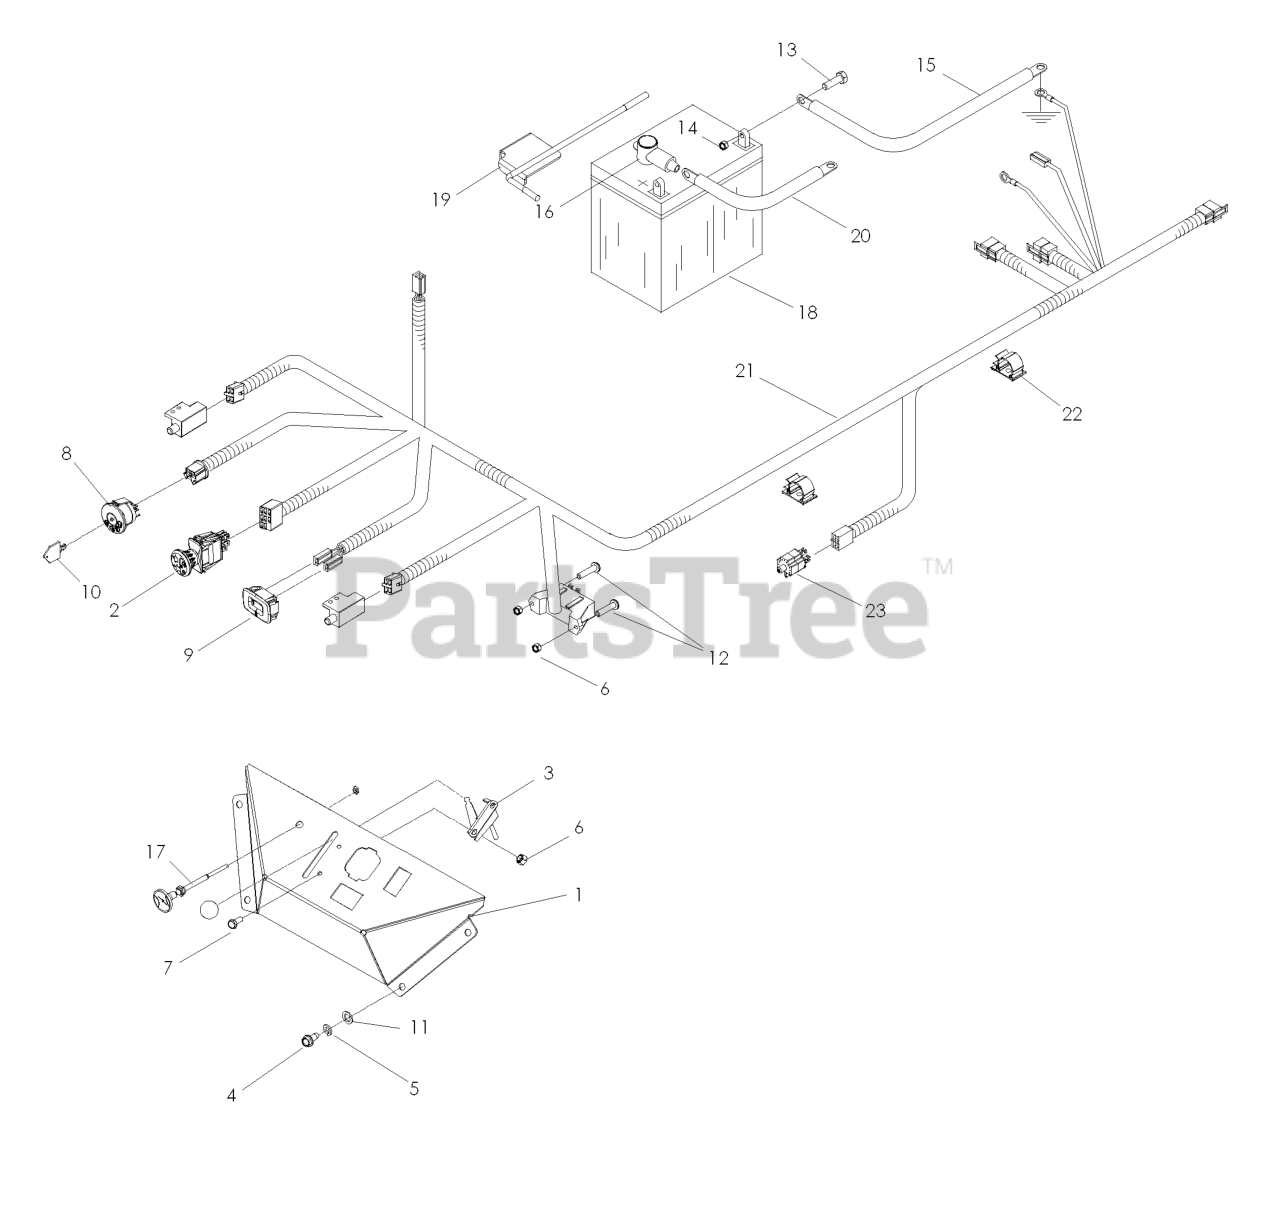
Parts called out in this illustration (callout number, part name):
1	CONSLE, ORANGE
2	SWITCH, PTO 10 AMP
3	THROTTLE CABLE
4	SCREW 1/4 X 5/8
5	LOCKWASHER 1/4"
6	NUT 10-24 NYLOC
7	HCS #10-24 X 1/2
8	RP IGNITION SWITCH
9	HOUR METER
10	KEY
11	WASHER 1/4 FLAT
12	SCREW, #1--24 X 1/2 SLOTTED
13	HCS 5/16C X 3/4
14	NUT 5/16 NYLOC
15	CABLE-NEGATIVE
17	CONTROL-CHOKE 51"
18	BATTERY, 12 V 330 AMP
19	BATTERY HOLD DOWN
20	CABLE POSITIVE, LONG
21	HARNESS, WIRING LZ/IZ
22	PUSH-MOUNT WIRE CLIP
23	SWITCH, BRAKE 3P
